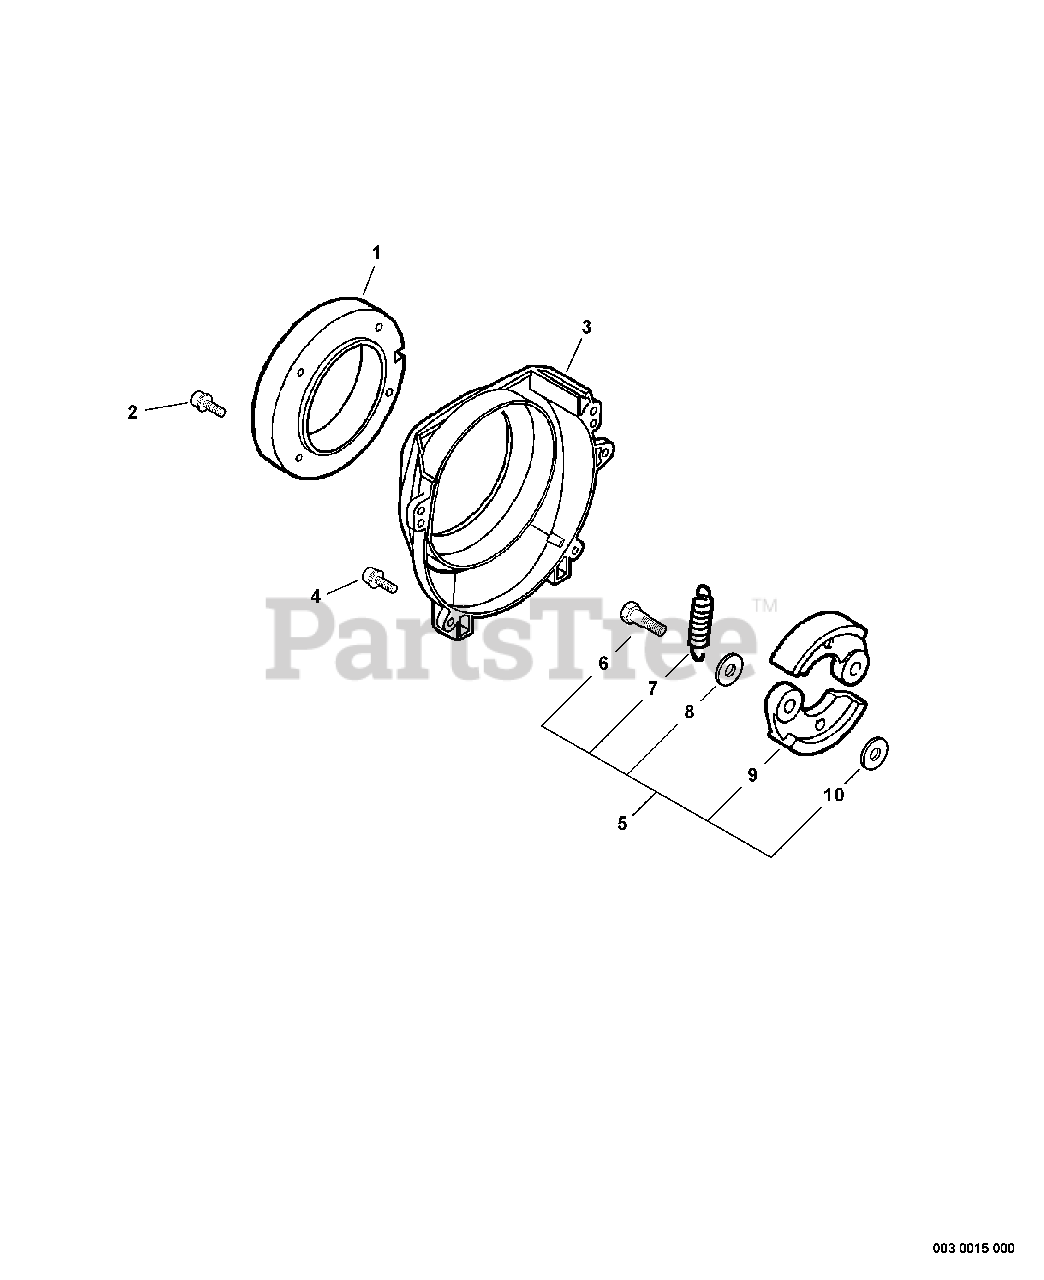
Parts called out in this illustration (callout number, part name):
1	PLATE, CLUTCH
2	BOLT 5×20
3	COVER, FAN
4	BOLT 5×20
5	CLUTCH ASSY
6	BOLT, CLUTCH
7	SPRING, TENSION
8	WASHER, WAVE
9	SHOE, CLUTCH
10	WASHER 8.2×17×1.6
